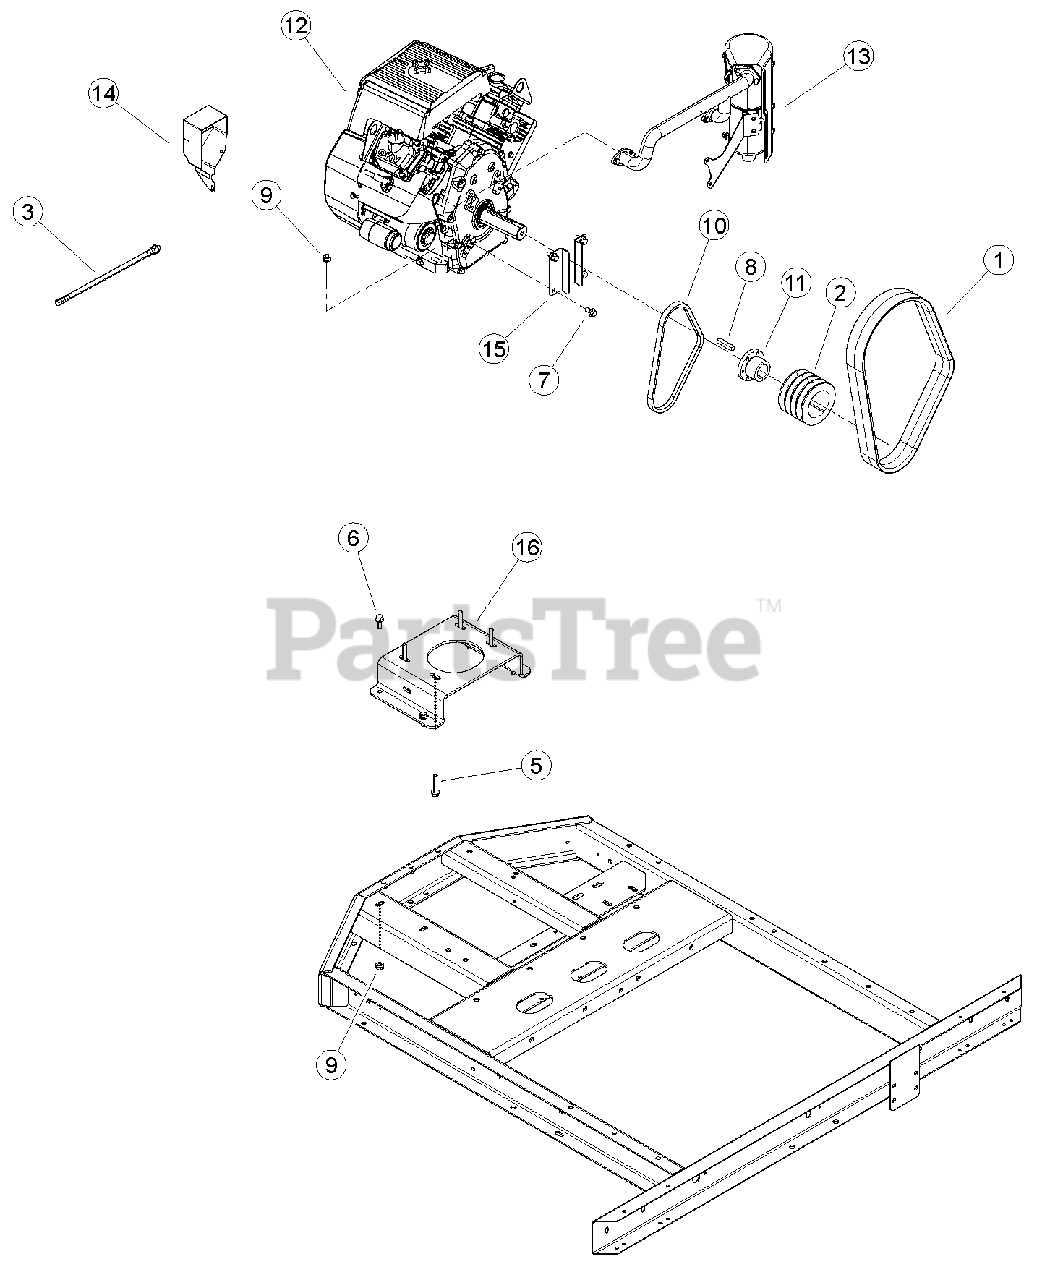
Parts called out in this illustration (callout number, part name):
1	BELT, 3RB48 ARAMID
2	SHEAVE, 4B4.2 SD
3	HOSE ASSEMBLY, CRANKCASE DRAIN
4	BOLT, 3/8 X 1" GR5 CRG NC ZP
5	BOLT, 3/8 X 2 FLANGE NC
6	BOLT, 3/8 X 1 FLANGE NC
7	BOLT, 3/8 X 3/4 FLANGE NC
8	KEY, 3/8" SQ X 2" LG PLAIN
9	NUT, 3/8-16 NYLOCK FLANGE
10	BELT, 29" C/S
11	BUSHING, SD 1-7/16"
12	ENGINE, SUBARU 720CC EH72 (FOR SERVICE SEE ENGINE OWNER'S MANUAL OR YOUR NEAREST SUBARU INDUSTRIAL ENGINE DEALER)
13	MUFFLER, SUBARU V-TWIN OIL SIDE (FOR SERVICE SEE ENGINE OWNER'S MANUAL OR YOUR NEAREST SUBARU INDUSTRIAL ENGINE DEALER)
14	CONTROL, SUBARU V-TWIN IGNITION/HOUR (FOR SERVICE SEE ENGINE OWNER'S MANUAL OR YOUR NEAREST SUBARU INDUSTRIAL ENGINE DEALER)
15	SHIELD, SUBARU CRANKSHAFT
16	BASE, SUBARU ENGINE
